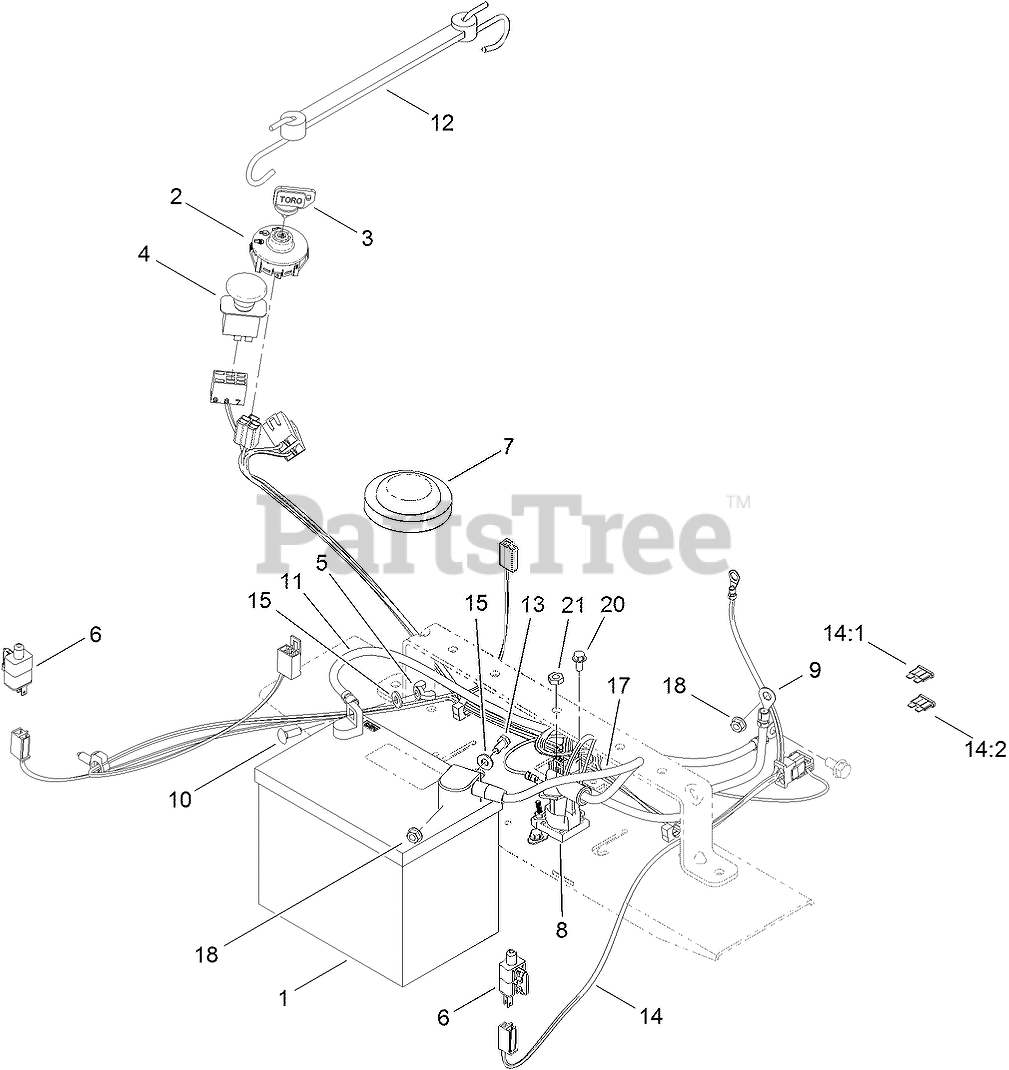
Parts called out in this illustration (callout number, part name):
1	BATTERY
2	SWITCH-IGNITION
3	KEY-IGNITION
4	SWITCH-PTO
5	NUT-WING
6	SWITCH
7	SWITCH-SEAT
8	SOLENOID
9	CABLE-BATTERY, RED
10	BOLT-CARR
11	CABLE-BATTERY, BLACK
12	HOLDDOWN-BATTERY
13	SCREW-HH
14	HARNESS-WIRE
14:1	FUSE-BLADE, 30 AMP
14:2	FUSE-BLADE, 25 AMP
15	WASHER-FLAT
17	CABLE-BATTERY, RED
18	NUT-HF
20	SCREW-HWH
21	NUT-JAM
